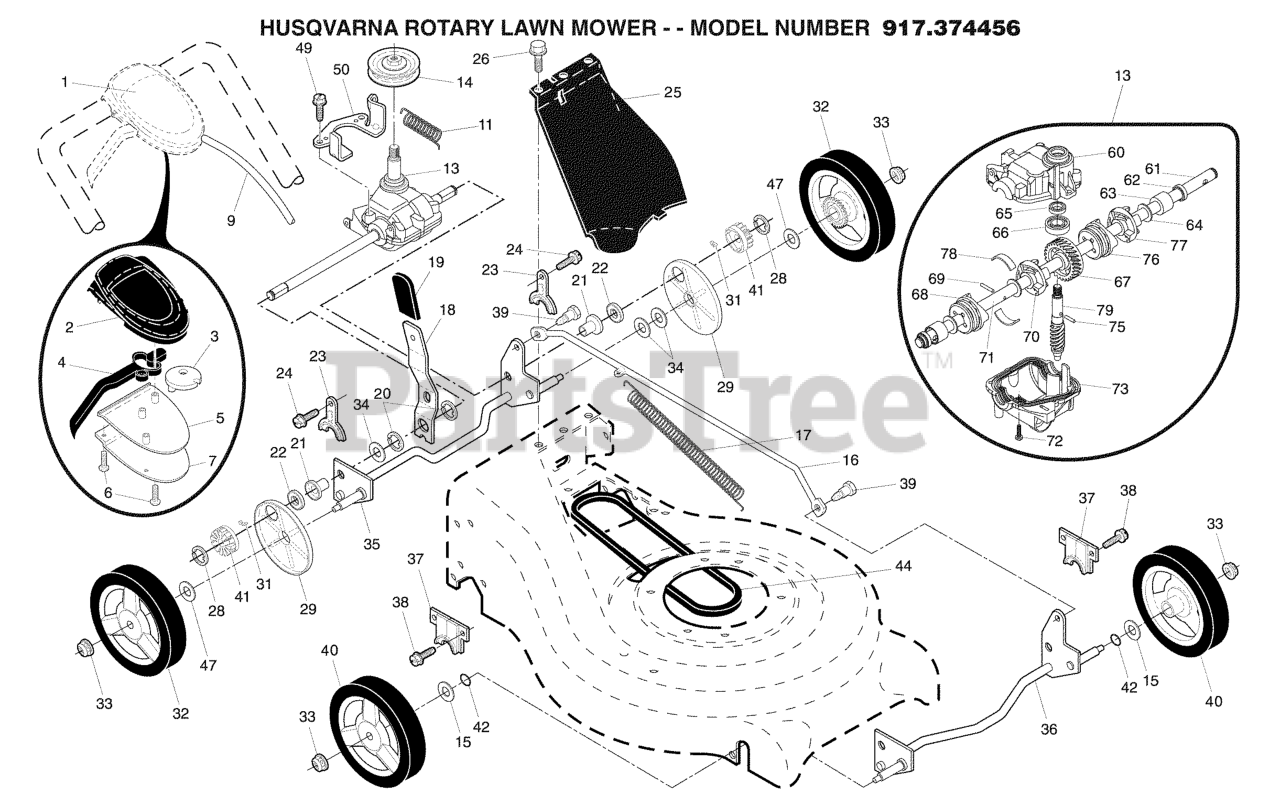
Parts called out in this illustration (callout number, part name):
1	Drive Control Assembly
2	Cover, Top
3	Pulley
4	Lever, Drive Control
5	Cover, Bottom
6	Screw
7	Mounting Bracket
9	Cable, Drive
11	Spring, Return
13	Gear Case Assembly
14	Pulley, Drive
15	Washer, Flat
16	Rod, Connecting
17	Spring, Extension
18	Spring, Selector
19	Knob, Selector Spring
20	E-Ring 7/8
21	Bearing, Support
22	Bearing, Ball
23	Retainer, Drive Assembly
24	Screw, Tapping, Hex Head 1/4-20 x 3/4
25	Cover Drive
26	Screw, Threaded, Rolled #10-25 x .50
28	E-Ring 7/16
29	Cover, Dust, Wheel
31	Pawl
32	Wheel & Tire Assembly, Rear 8 x 1-3/4
33	Nut, Flangelock 3/8-16
34	Washer
35	Shaft Assembly, Rear
36	Shaft Assembly, Front
37	Retainer, Front Shaft
38	Screw #12 x 5/8
39	Bolt, Shoulder, Semi-Gimlett Point
40	Wheel & Tire Assembly, Front 8 x 1-3/4
41	Pinion
42	O-Ring
44	V-Belt
47	Washer, Flat
49	Screw, Hi-Lo Thread
50	Belt Keeper
60	Case, Upper
61	Shaft, Output, Long
62	Seal, Output Shaft
63	Bushing
64	Washer
65	Seal, Worm Shaft
66	Bearing, Ball
67	Gear, 28 Teeth
68	Fixed Dog Clutch, LH
69	Pin, Output Shaft
70	Movable Dog Clutch, LH
71	Shaft, Output, Short
72	Screw, Case
73	Case, Lower
75	Pin, Worm Shaft
76	Movable Dog Clutch, RH
77	Fixed Dog Clutch, RH
78	Spring, Leaf
79	Shaft, Worm
